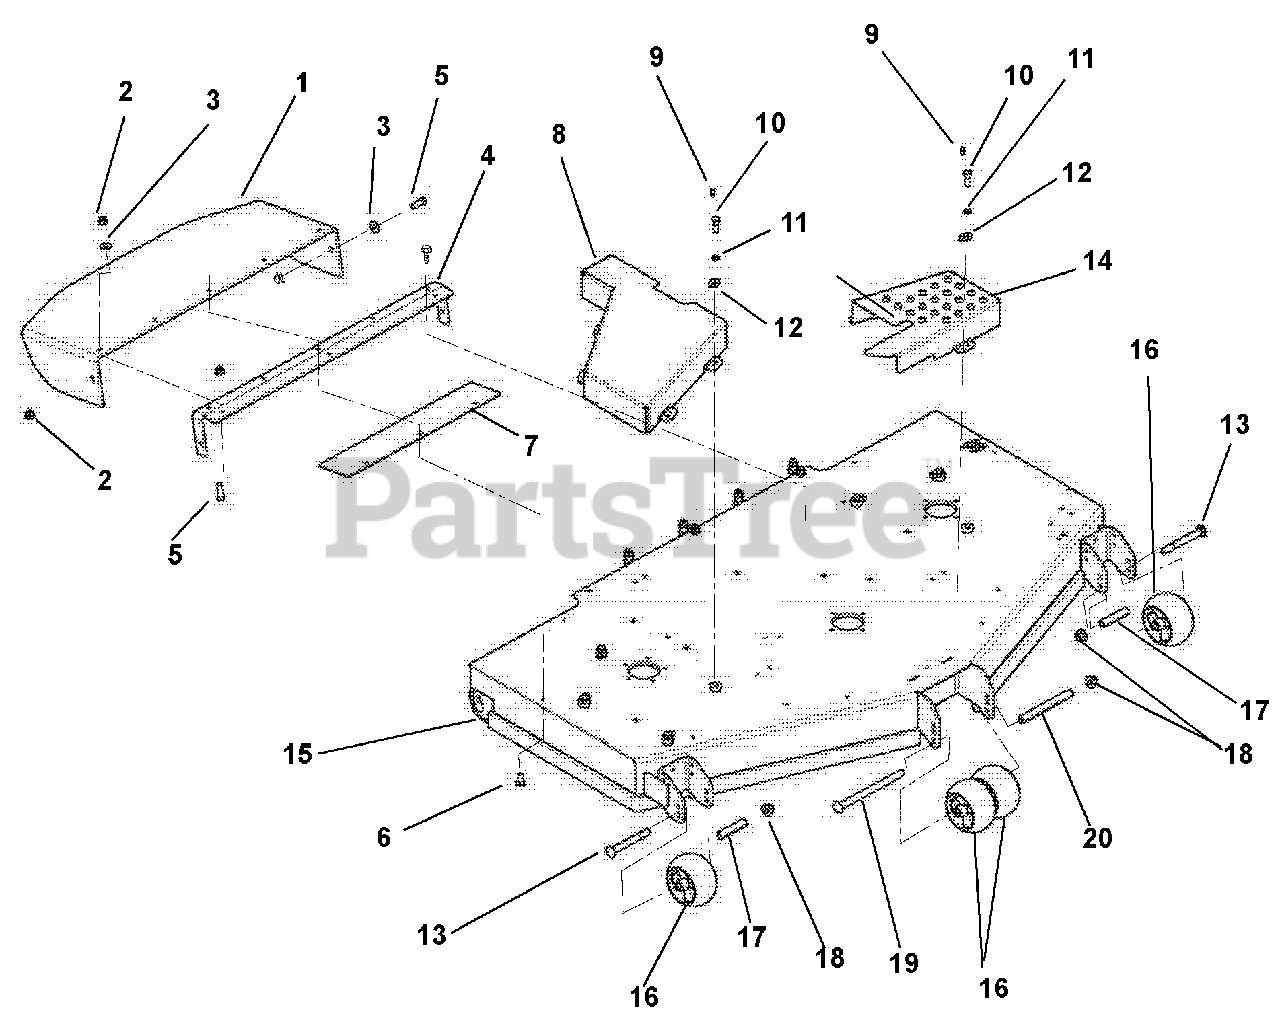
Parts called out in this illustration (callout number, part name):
1	Chute, Rubber Discharge
2	Nut, Locking, Nyloc, Flange .38-16
3	Washer, Flat Steel .438 x 1.00 x .083
4	Support, Rubber Discharge Chute
5	Bolt, Hex .38-16 x 1.25
6	Bolt, Round Head Square Neck .38-16 x 1.00
7	Plate, Discharge Chute Support
8	Guard, Belt, Right – 60" Deck
9	Rivet, Pop, 0.187
10	Bolt, Hex 0.38-16 x 1.25
11	Washer, Locking, Ext. 0.391 x 0.628 x 0.036
12	Keeper, Bolt
13	Bolt, Round Head Square Neck .50-13 x 5.00
14	Guard, Belt, Spindle Left Hand
15	Weldment, 60" Rear Discharge Deck
16	Anti-Scalp Wheel
17	Spacer, .510 x .625 x 3.35
18	Nut, Locking, Nyloc Flange .50-13
19	Bolt, Round Head Square Neck .50-13 x 8.50
20	Spacer, .510 X .625 x 6.70
